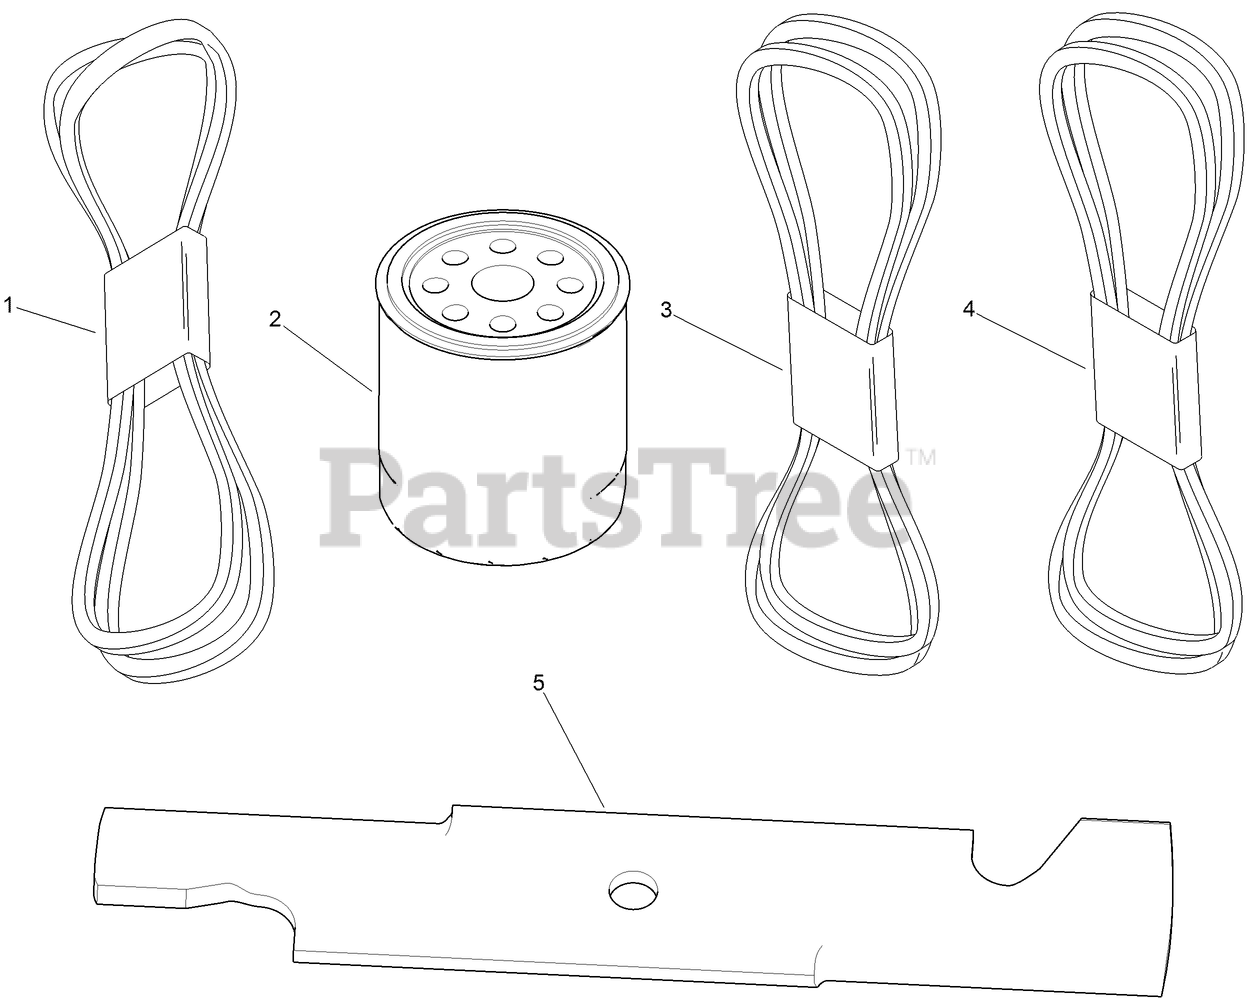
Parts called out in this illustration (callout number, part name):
1	BELT-V
2	ELEMENT-FILTER, 25 MICRON
3	BELT-V
4	BELT-V
5	BLADE-14 INCH (HIGH SAIL)
